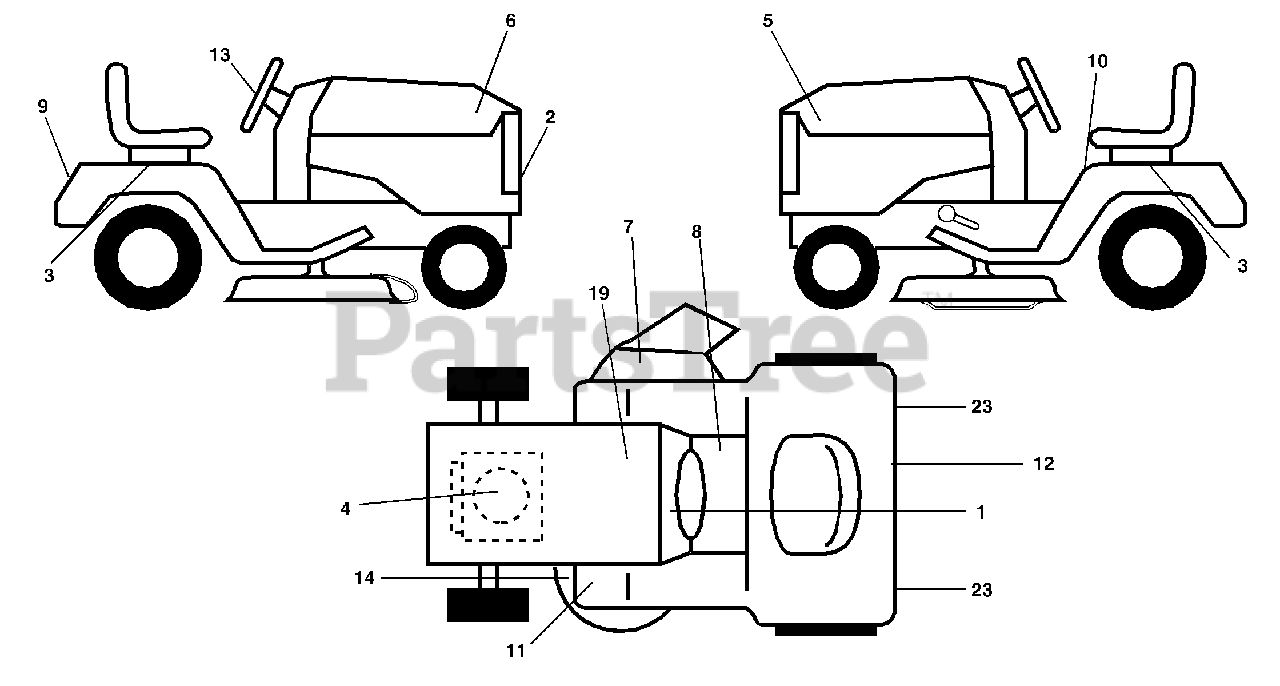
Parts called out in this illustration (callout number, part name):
1	Decal, Operating Instruction
2	Decal, Grille Husqvarna
3	Decal, Fender Automatic
4	Decal, HP Engine
5	Decal, Inst Hood LH GTH220 Hydro
6	Decal, Insrt Hood RH GTH220 Hydro
7	Decal, Warning Multi-Language
8	Decal, Brake Parking Saddle
9	Decal, Fender
10	Decal, Danger
11	Decal, Clutch/Brake
12	Decal, D-Bar Ctrl. Mvt Hyd YT/GT
13	Decal, SW Deluxe
14	Decal, V-Belt Schematic
19	Decal, Battery
23	Reflector, Taillight
